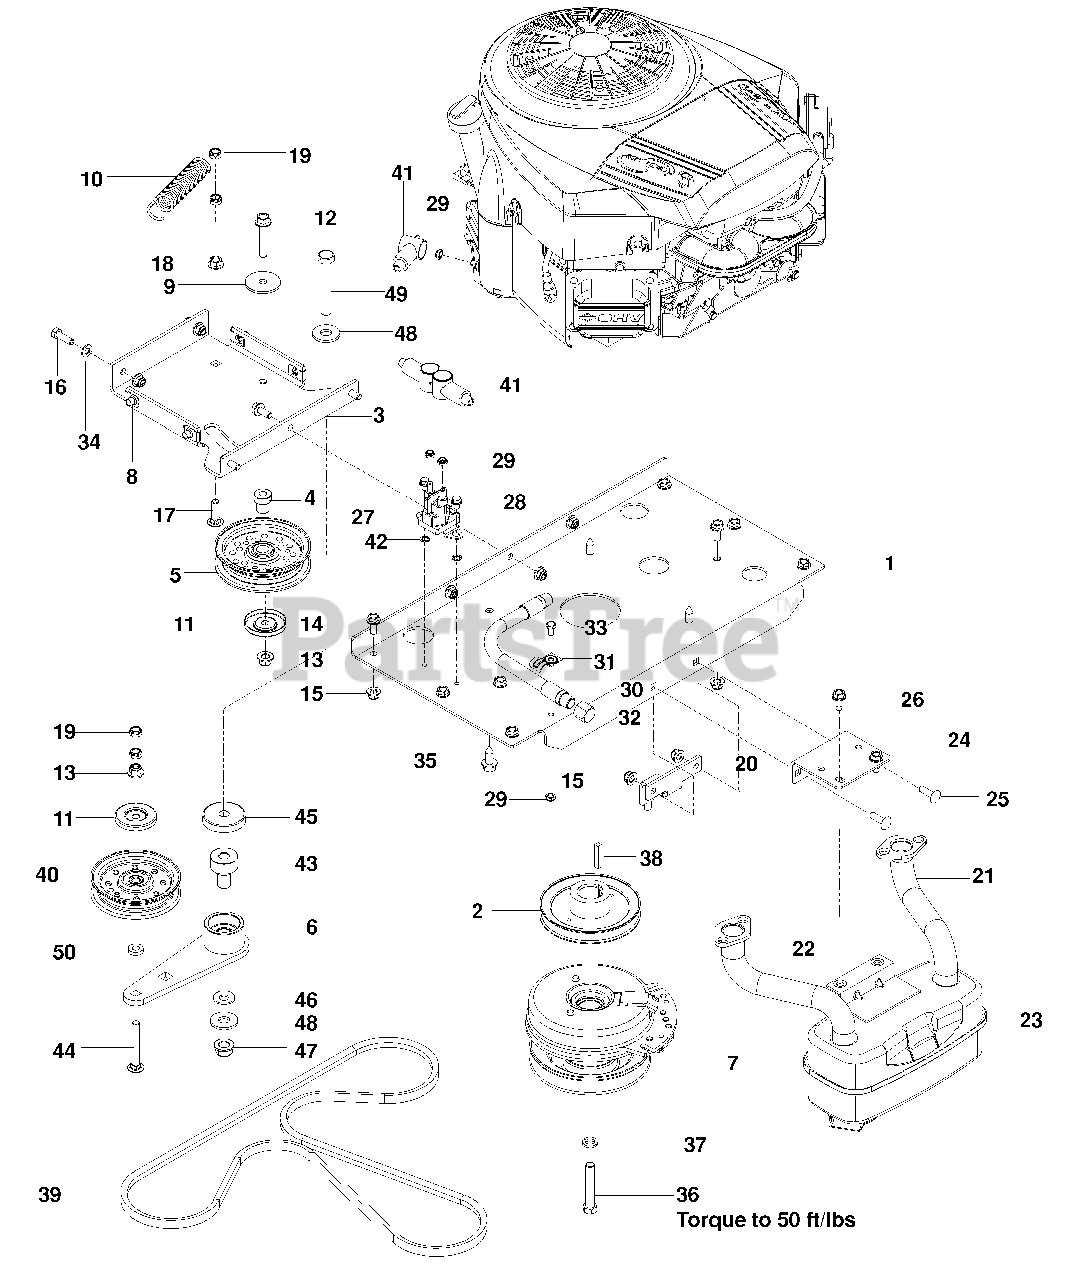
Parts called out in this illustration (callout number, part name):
1	PLATE, ENGINE w/ DECAL
2	PULLEY, V 1 1/8 BORE
3	PLATE, IDLER SUPPORT
4	PIVOT, IDLER
5	PULLEY, IDLER
6	ARM, IDLER w/ BEARINGS
7	CLUTCH, 200 FT-LB
8	RETAINER, U TYPE 5/16-18
9	WASHER, SPECIAL
10	SPRING, PUMP
11	SHIELD, DUST
12	HHFS 3/8-16 x 2
13	NUT 3/8-16 HEX FLG NYLOC
14	HHFS 5/16-18 x 3/4
15	NUT 5/16-18 HEX FLG NYLOC
16	HCS 5/16-18 x 1
17	RHSNB 3/8-16 x 1 1/4
18	NUT 3/8-16 HEX WHIZLK
19	NUT 3/8-16 HEX JAM NYLOC
20	STOP, CLUTCH
21	EXHAUST TUBE, RT
22	EXHAUST TUBE, LT
23	MUFFLER ASM TWIN
24	BRKT, MUFFLER, BLK
25	RHSSNB 5/16-18 x 1
26	BOLT 5/16-18 x 3/4 THD FRM
28	SCREW 1/4-20 x 8 THD FRM
29	NUT 1/4-20 HEX THIN NYLOC
30	HOSE-DRAIN
33	HCS 1/4-20 x 2
34	WASHER 5/16 SAE FLAT
35	HHFS 3/8-16 x 1 THD FRM
36	HCS 7/16-20 x 21/2
37	WASHER 7/16 SLW
38	KEY 1/4 SQ x 1 1/4
40	PULLEY, IDLER SECONDARY
42	WASHER 1/4 INT TOOTH LK
43	PIVOT, BEARING
44	RHSNB 3/8-16 x 23/4
45	SHIELD, DUST
46	WASHER 1/2" BELLEVILLE
47	NUT 1/2-13 HEX FLG NYLOC
48	WASHER 1/2 FLAT ZD
49	HCS 1/2-13 x 3 1/4
50	WASHER 3/8 x 3/4
